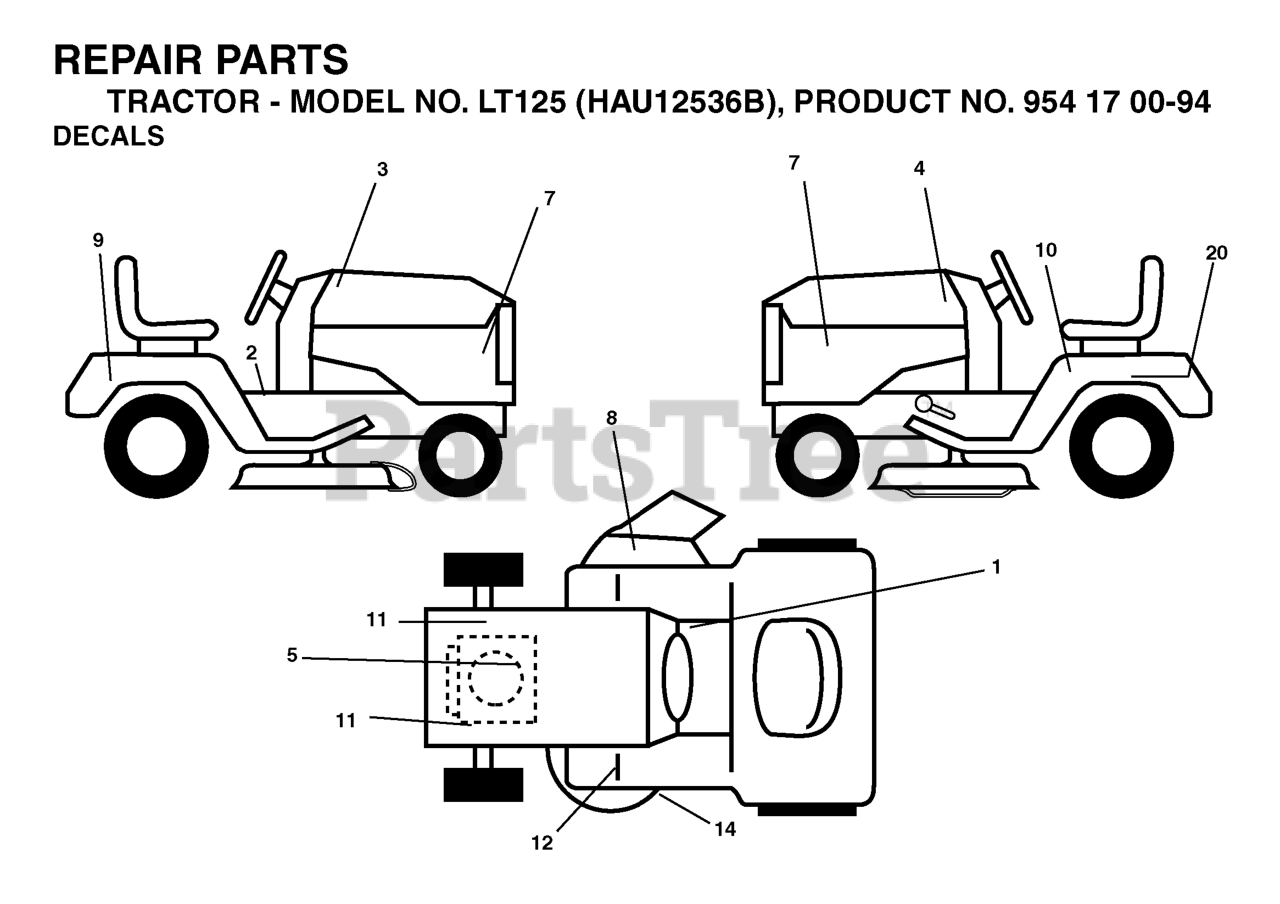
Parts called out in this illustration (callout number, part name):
1	DECAL
2	DECAL PARK BRAKE
7	DECAL PNL SIDE
8	DECAL.INTERNATIONL.CUTFINGER
9	DECAL FENDER HUSQ
10	DECAL READ OWNER'S MAN SYMS
12	DECAL
14	DECAL V-BELT SCHEMATIC
20	DECAL BTRY SYMBOLS
